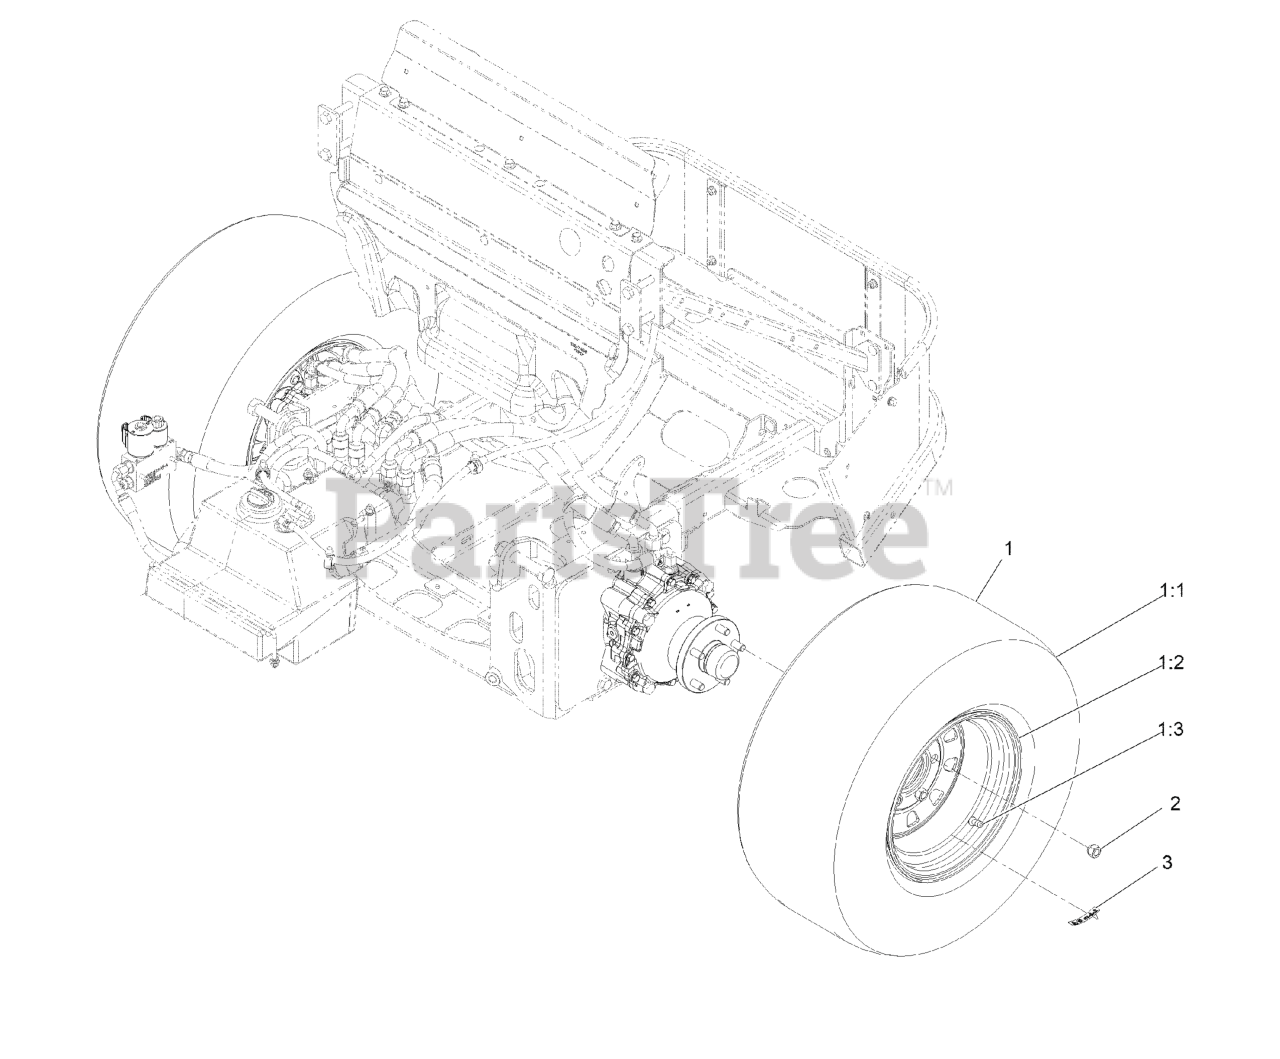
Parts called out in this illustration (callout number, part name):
1	ASM-TIRE 26 X 12-12
1:1	RIM ASM
1:3	Stem-Valve
2	NUT-LUG
3	DECAL-TORQUE, WHEEL NUT
